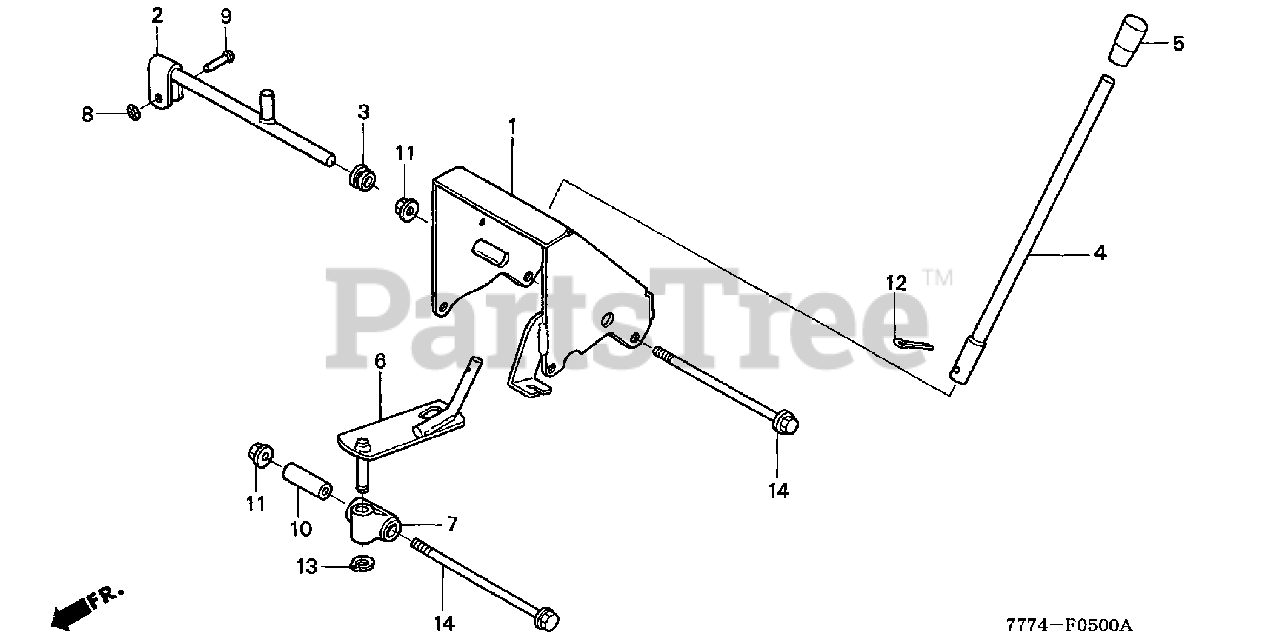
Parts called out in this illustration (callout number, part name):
1	COVER, CHANGE *R8* (BRIGHT RED)
1	COVER, CHANGE *R280* (POWER RED)
2	ARM, CHANGE
3	BUSH, CHANGE ARM
4	LEVER, CHANGE
5	GRIP, CHANGE LEVER
6	LEVER, SELECT
7	HOLDER, SELECT LEVER
8	WASHER, SPECIAL (5MM)
9	PIN, CHANGE (5X23)
10	COLLAR, SELECT LEVER HOLD
11	NUT, FLANGE (8MM)
12	PIN, COTTER (2.5MM)
13	CIRCLIP, OUTER (12MM)
14	BOLT, FLANGE (8X140)
